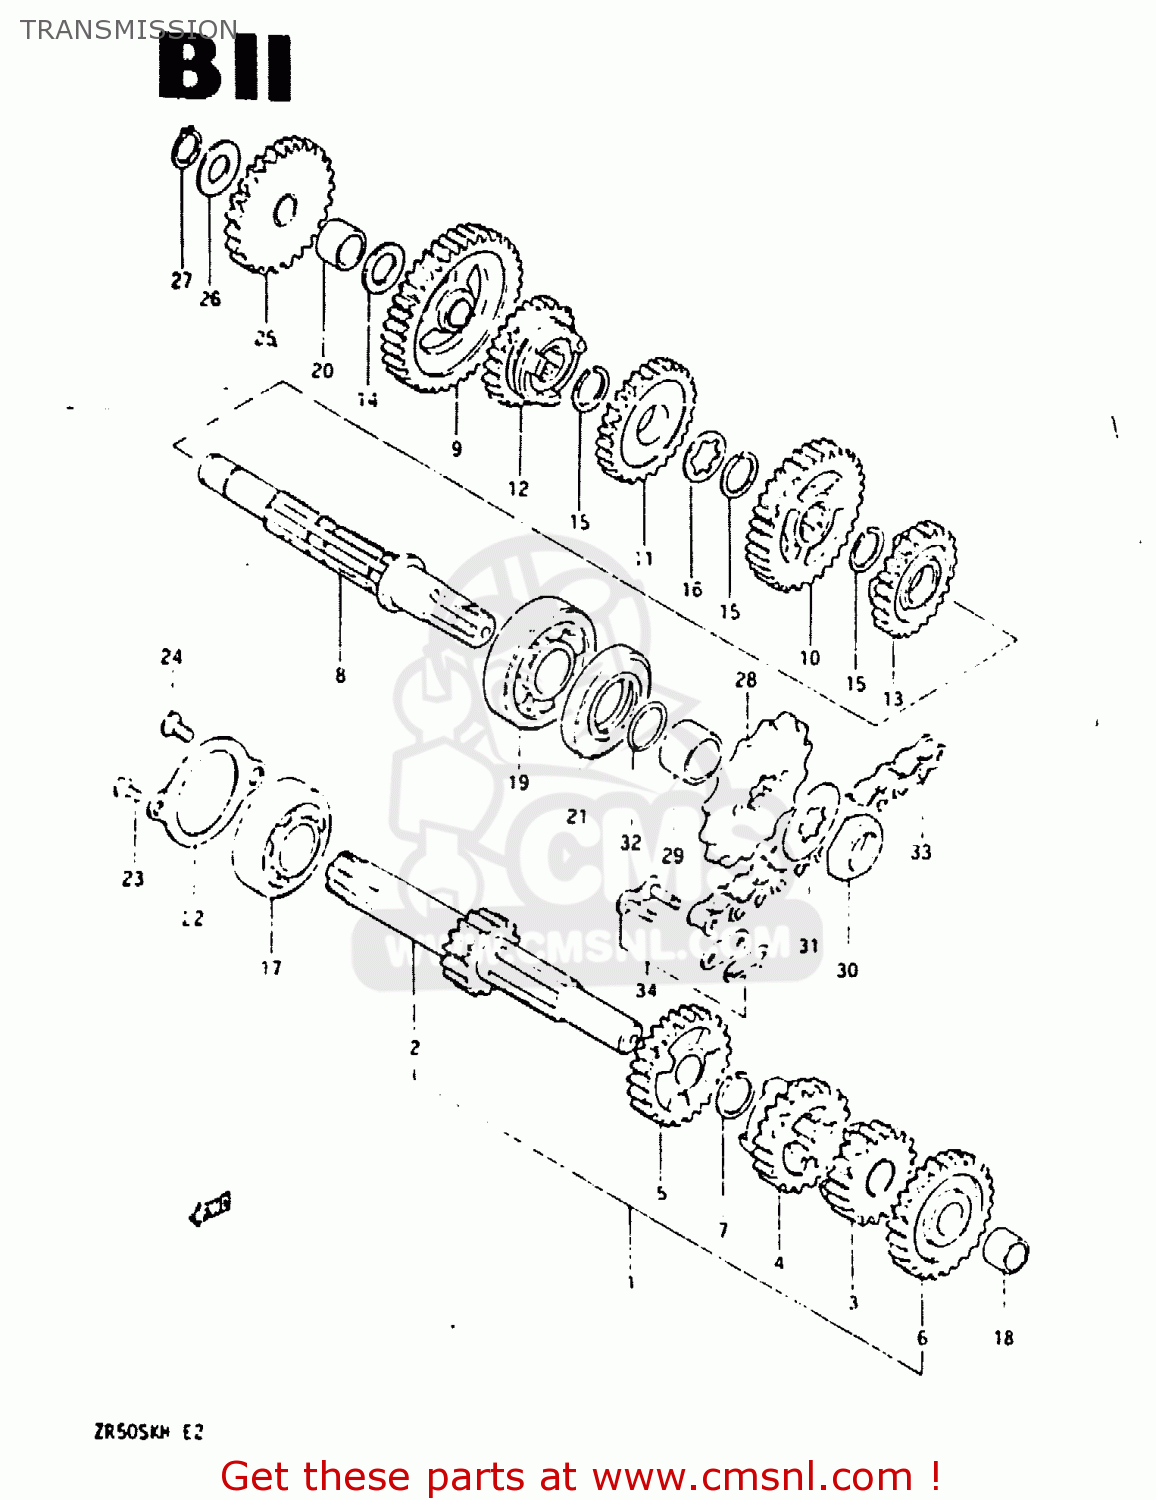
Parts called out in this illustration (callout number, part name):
1	SHAFT,COUNTER
2	SHAFT,COUNTER(NT:12)
3	GEAR,SECOND DRIVE
4	GEAR,THIRD DRIVE
5	GEAR,4TH DRIVE(NT:24)
6	GEAR,FIFTH DRIVE
7	CIRCLIP
8	SHAFT,DRIVE
9	GEAR,FIRST DRIVEN
10	GEAR,2ND DRIVEN(NT:33)
11	GEAR,3RD DRIVEN(NT:29)
12	GEAR,FOURTH DRIVEN
13	GEAR,5TH DRIVEN(NT:24)
14	WASHER(13X24X1)
15	CIRCLIP
16	WASHER,LOCK
17	BEARING(17X40X12)
18	BUSH
19	BEARING
20	BUSH
21	SEAL,OIL(21X40X6)
22	RETAINER,CNTR SHAFT BEARING
23	SCREW
24	SCREW
25	GEAR,KICK STARTER IDLE
26	WASHER
27	CIRCLIP
28	SPROCKET,ENGINE
29	SPACER(17X21X13)
30	NUT
31	LOCK WASHER
32	O RING(D:1,ID:16.8)
33	CHAIN ASSEMBLY,DRIVE
34	JOINT
